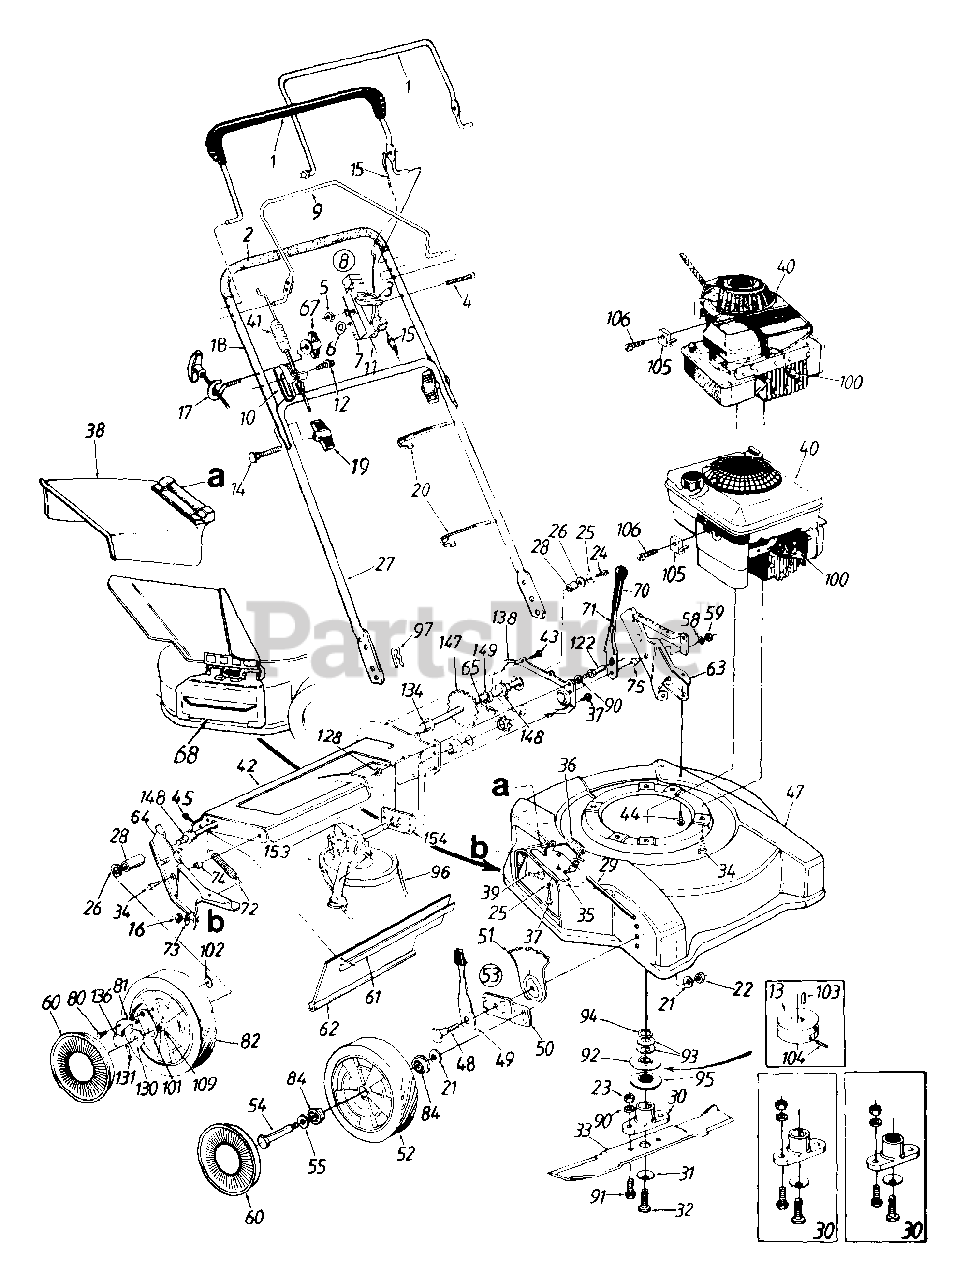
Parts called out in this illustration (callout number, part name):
2	Foam Grip
3	Throttle Lever
4	Oval C-Sunk Scr.
5	Hex L-Nut 1/4-20 Thd.
6	Spr. Wash..66" I.D.
7	Throttle Body
8	Throttle Box Comp.
11	Throttle Cable 55" Lg. (B&S)
12	Hex Wash. AB-Tap Scr. 5/16 x .75" Lg.
13	Keyed Pulley
14	Curved Hd. Bolt 5/16-18 x 2"
15	Control Cable 39" Lg. (B&S)
16	Hex Nut 5/16-18 Thd.
17	Rope Guide
20	Cable Tie
21	Bell-Wash..38" I.D. x .88"
22	Hex Nut 3/8-16 Thd.
23	Hex Nut 3/8-24 Thd.
24	Hex Bolt 1/4-20 x .62" Lg. (Grade 5)
25	Bell-Wash. 1/4" I.D.
26	Fl-Wash..531" I.D. x .93"
28	Spacer .513" I.D. x .703"
29	Hinge Pin
30	Blade Adapter Kit
31	Bell-Wash..39" I.D.
32	Hex Bolt 3/8-24 x 1.5" Lg.
33	22" Blade
34	Hex L-Wash. Hd. Scr. 3/8-16 x 1.0" Lg.
35	Adapter Plate
36	Torsion Spring
37	Hex Self-Tap Scr. 1/4-20 x .5"
38	Chute Deflector Ass'y.
39	Carriage Bolt 5/16-18 x .62" Lg.
40	Engine
41	Drive Cable - 41.5" Lg.
44	Hex Wash. Hd. B-Tap Scr. 5/16-18
45	Hex AB-Tap Scr. 1/4 x .62"
49	Spring Lever Ass'y. w/Knob
51	Height Adj. Plate
52	Wheel Ass'y. Comp.
53	Height Adj. Ass'y. Comp.- R.H.
54	Shld. Bolt .498" Dia. x 1.45"
55	Wave Wash..51" I.D. x .78"
58	Fl-Wash..385" I.D. x.87"
59	Hex Patch L-Nut 3/8-24 Thd.
60	Hub Cap
61	Retaining Strip
62	Rear Flap
63	L.H. Handle Wheel Brkt. Ass'y.
64	R.H. Handle Wheel Brkt. Ass'y.
65	#48 Chain .5" Pitch x 30 Links
67	Wing Nut 1/4-20 Thd.
68	Mulching Baffle
71	Height Adj. Lever
72	Ext. Spring .5" O.D. x 3.8" Lg.
73	Bell-Wash. 5/16" I.D.
74	Spacer .383" I.D. x .503"
75	Shld. Spacer .5" Dia.
80	Shld. Scr..342" Dia. x .268"
81	Pawl
82	Wheel Ass'y. Comp.
84	Bearing
90	L-Wash. 3/8" I.D.
91	Hex Bolt 3/8-24 x 1.0" Lg.
92	Splined Pulley Half
93	Bell-Wash. 1.01" I.D.
94	Crankshaft Spacer
95	Lower Pulley Half
96	"V"-Belt
97	Hairpin Clip
100	Spark Plug Boot
101	Pawl Plate
102	Weld L-Nut 1/4-20 Thd.
103	Sq. Key 3/16" x 3/4" Lg.
104	Set Scr. #10-32 x .25" Lg.
105	Cable Clamp (B&S)
106	Hex Wash. Hd. Scr. #10-32 x .62" Lg. (B&S)
109	Sleeve Brg. 1/2" I.D.
122	Shld. Pin 3/8-24 x 1.43" Lg.
128	Hex Jam Nut 3/8-24 Thd.
130	Ratchet Wheel 1.62" O.D.
131	Cotter Pin 1/8" Dia.
134	Hex Flange Bearing
136	Spring - Nylon
148	Hex Flange Bearing
149	Fl-Wash..531" I.D. x.93"
153	Transmission Comp (See Breakdown)
